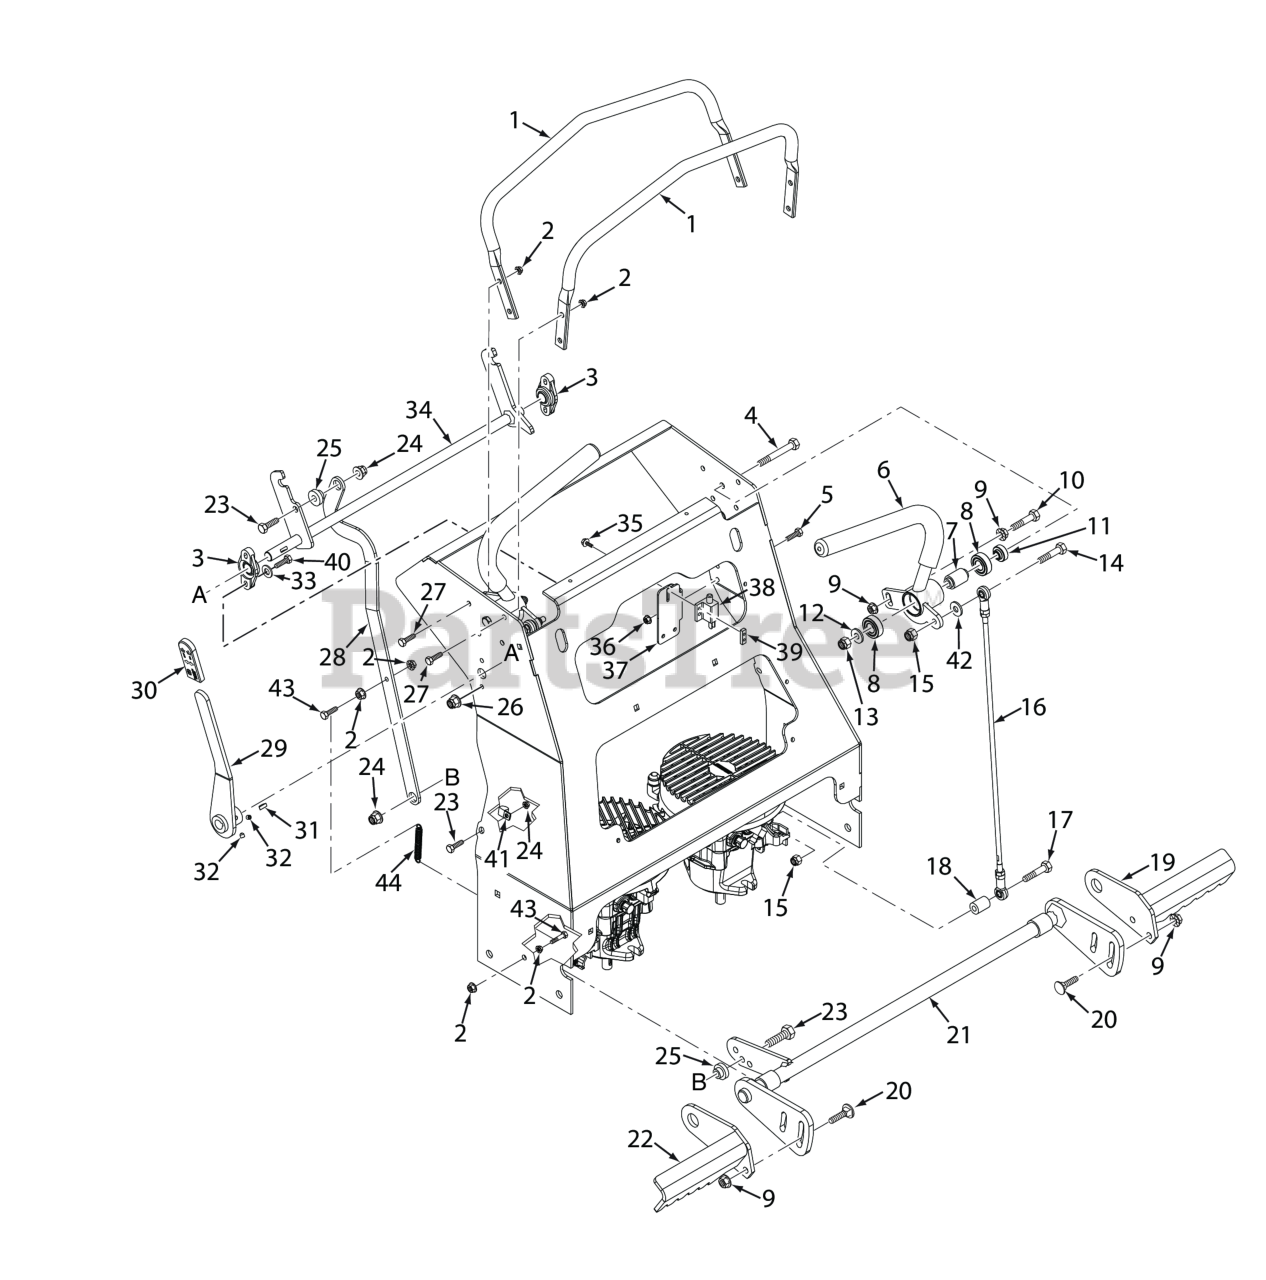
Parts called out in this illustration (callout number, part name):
1	Reference Bar
2	Nut, Serrated Flange 5/16-18 (Right Front Engine Mounting, Briggs and Kohler Only)
3	Bearing
4	Capscrew, Hex Head 3/8-16 x 3.25"
5	BOLT, HEX HEAD, 1/4-20 X 3/4 GR.5
6	Handlebar Assy., LH
7	Spacer, Bearing
8	BEARINGS, BALL, NEUTRAL RETURN
9	NUT, 3/8-16 SERRATED FLANGE HEX HEAD
10	Capscrew, Hex Head 3/8-16 x 2.0"
11	Spacer, Controls
12	Flatwasher, 3/8 (.391 x .938 x .105 HD) Grade 8
13	HEX NUT, ELASTIC STOP LOCK, 3/8-16
14	Bolt, 5/16 - 18 x 1 - 1/4" Hex Head
15	HEX NUT, ELASTIC STOP LOCK, 5/16-18
16	Linkage Assy., Steering
17	Bolt, Hex Head 5/16-18 x 2-1/2" (x3) (35BV & 37BV-EFI)
18	Spacer (excludes SVRII-36A)
19	Brake Paddle Weldment, RH
20	Carriage Bolt, 3/8-16 x 1.0"
21	Bellcrank Weldment, Brake
22	BRAKE PADDLE WLMT, LH
23	Bolt, Hex Head 3/8-16 x 1-1/4", Kawasaki FX / FT & FT-EFI
24	Nut, Flange Elastic Stop Nut, 3/8-16
25	BUSHING, BRONZE - .376 ID X .627 OD
26	Nut, Flanged Elastic Stop 1/4-20
27	BOLT, SERRATED FLANGE HEX HEAD 5/16-18 X 3/4"
28	Link, Brake Engage
29	Lever Assembly, Brake, SVRII
30	Grip, Brake Handle
31	KEY, 3/16 X 3/16 X 1-1/2
32	Set Screw 1/4-20 x 1/4"
33	Flatwasher, 1/4 (.281 x .625 x .065)
34	Lock Weldment, Neutral
35	Screw, Hex-Slotted Washer Head #10 32 x 3/4"
36	NUT, 1/4-20 SERRATED FLANGE HEX HEAD
37	Bracket, Neutral Switch
38	Switch, Interlock, Park Brake Normally Open
39	Plate, Threaded
40	Capscrew, Hex Head 1/4-20 x 1"
41	CLAMP, CABLE - 1.00
42	Flatwasher, 5/16-.344 x .688 x .065 (48V / 52V)
43	Bolt, Hex Head 5/16-18 x 1-1/2" (Right Front Engine Mounting, Briggs and Kohler Only)
44	Spring, Deck Lift
